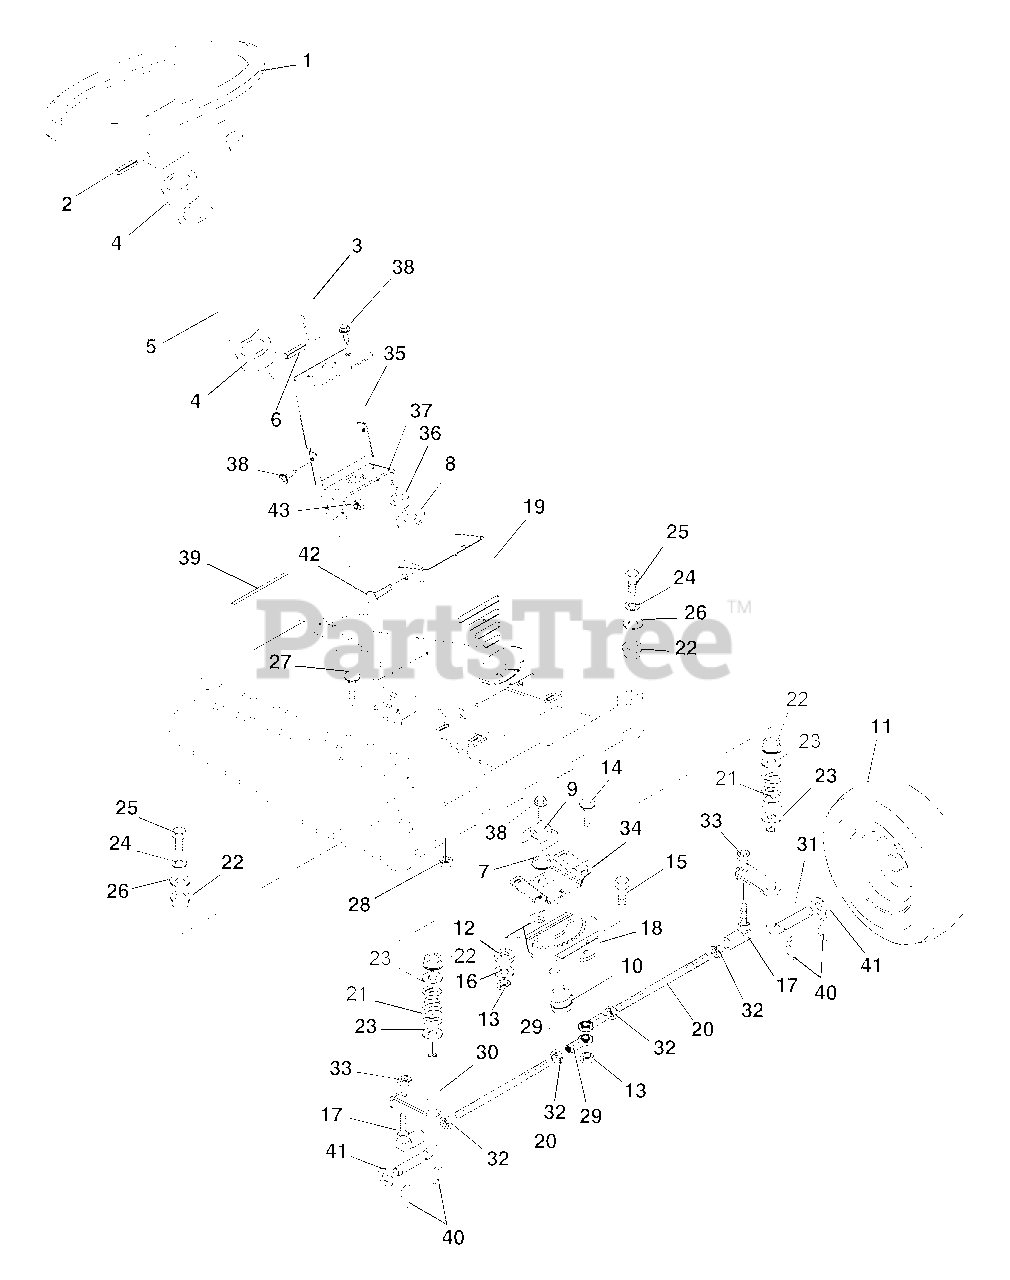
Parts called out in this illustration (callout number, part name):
1	STEERING WHEEL 13"
2	PIN-ROLL .250X1.75
3	STEERING SHAFT
5	TUBE 1.865 X 2.00 X 11.33
6	PIN-ROLL .188X.75
7	BSHG-FLG .625X1.156X.375 SI
8	WSHR-HDND-STL-THR.515X.97X.062
9	RETAINING PLATE
10	PINION
11	T/WHL ASSY
11	TIRE 4.10/3.50-4
11	BSHG-FLG .750X1.380X.750X1.557
12	STEER GEAR SPACER .38X.75X.269
13	NUT-LK-TOP-FLG .38-16 BLKZC
14	BLT-RDHDSQNK .38-16X1.00 G5BZ
15	@BLT-HEX .38-16X1.75 GR5 YWZC
16	WSHR-FL-STL .406X1.375X.135 YZ
17	BALL JOINT
18	STEERING GEAR
19	BOX, STEERING
20	STEERING LINK
21	SPRING, SUSPENSION
22	BUSHING-1"X.75"X1"
23	WSHR-FL-STL .700X1.47X.134 YWZ
24	@WSHR-LK .31X.078 REG YWZC
25	@BLT-HEX .31-18X.75 GR5 YWZC
26	WSHR-FL-STL .406X1.375X.135 YZ
27	BLT-RDHDSQNK .38-16X.75 G5BZ
28	NUT-LK-TOP-FLG .31-18 BLKZC
29	ROD END, .38 RH
30	WLDMT-SPINDLE (RH)
31	WLDMT-SPINDLE (LH)
32	NUT-JAM .375-24 YWZC
33	NUT-LK-NYL .375-24 W/INSR YWZC
34	STEERING GEAR SUPPORT
35	BRACKET, STEERING COLUMN
36	FLANGE BUSHING
37	SUPPORT-STEERING COLUMN
38	SCR-TAP .312-18X.50 HWH TR BL
39	COVER, LIGHT
40	PIN, SPRING CLIP
41	WSHR-FL-STL.755X1.375X.062YWZC
42	BLT-RDHDSQNK .31-18X.75 G5BZ
43	@NUT-LK-NYL .312-18 YWZC
